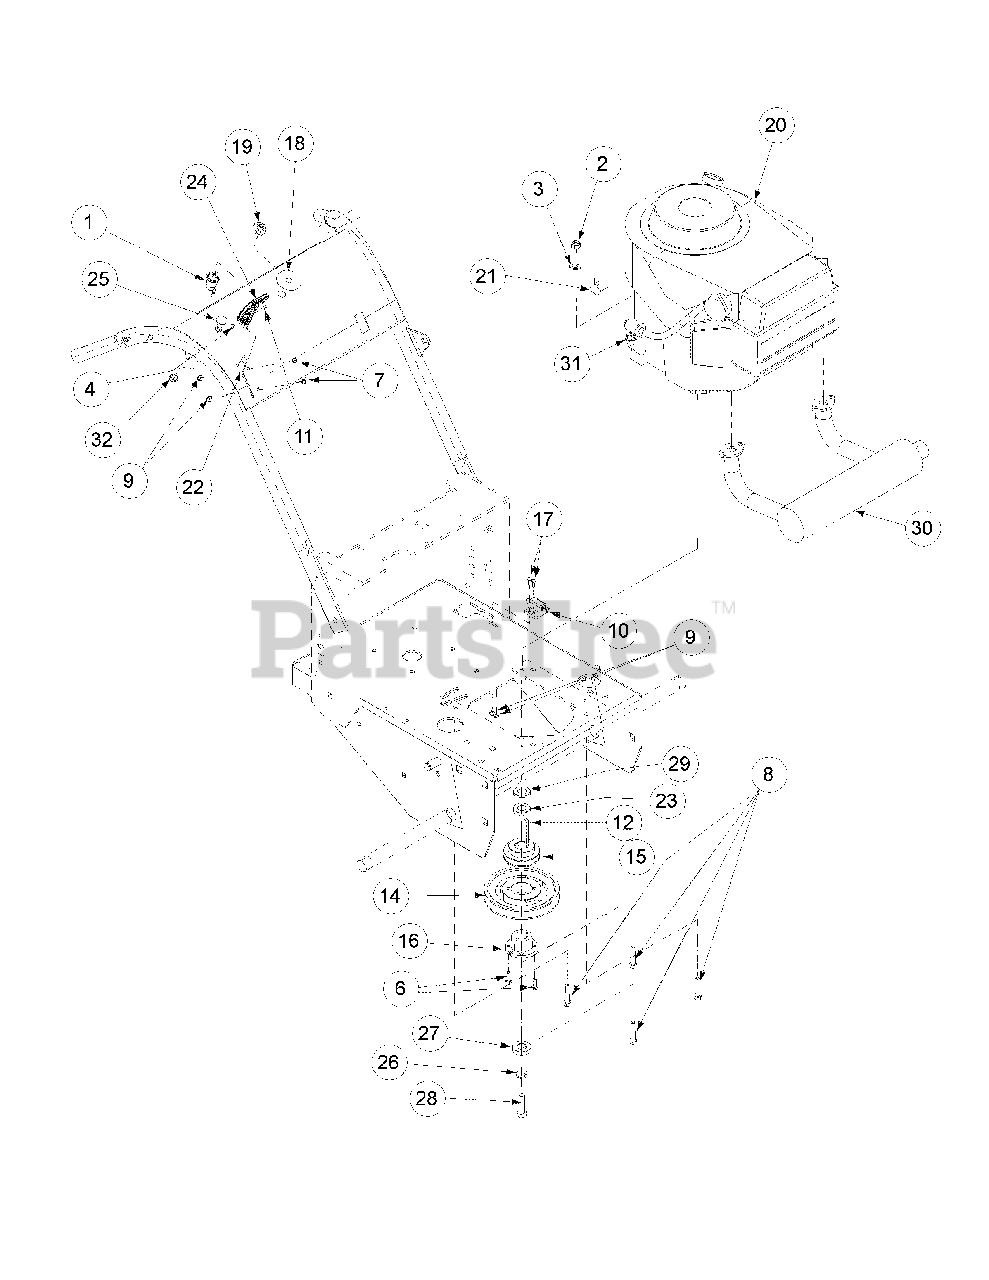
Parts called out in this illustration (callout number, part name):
1	Ignition ON/OFF Switch
2	Lock Nut, Nylon Insert, 5/16-18
3	Flat Washer, 5/16 Zinc
4	Nut, 8-32, w/ Star Washer
6	Hex Cap Screw, 1/4-20 x 3/4
7	Screw, Hex Washer, 10-32 x 1/2
8	HHCS, 5/16-18 x 1-3/4
9	Lock Nut, Nylon Insert, 10-32
10	Delta Switch
11	Machine Screw, 8-32 x 3.8
12	Key Stick, 1/4 x 1/4 x 2-3/4
14	Deck Pulley
15	Traction Pulley
17	Machine Screw, 10-32 x 5/8
18	Decal, Pull Start Overlay
19	Nut w/cap, 5/8-32 Ignition
20	13 Hp Kawasaki Kai Engine
21	Support Clamp, 3/8 OD
22	Throttle Control Cable
23	Flat Washer
24	Throttle Control Knob
25	Choke Cable
26	Lock Washer, 7/16
27	Clutch Washer
28	HHCS, M10 x 1.5, 30mm, GR10.9
29	Spacer, Engine Pulley
31	Hex Nut, 5/16-18
32	Jam Nut, 3/8-24
